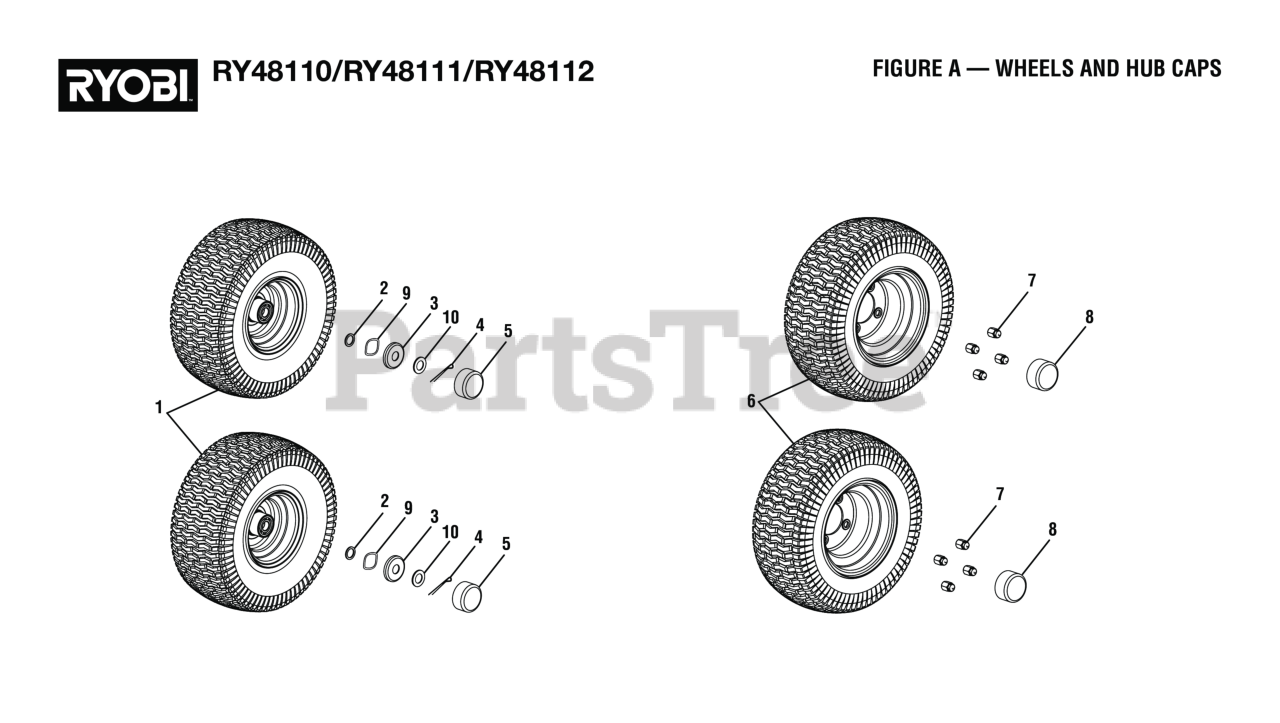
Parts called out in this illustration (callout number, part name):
1	Front Wheel Assembly
2	Washer (OD28 x ID20.5 x 2t)
3	Front Wheel Bearing Cover
4	Cotter Pin (4 x 40 mm)
5	Dust Cover, Front Wheel
6	Rear Wheel Assembly
7	Acorn Nut (M14)
8	Wheel Hub Cover
9	Wavy Washer
10	Washer (OD37 x ID21 x 0.3t)
